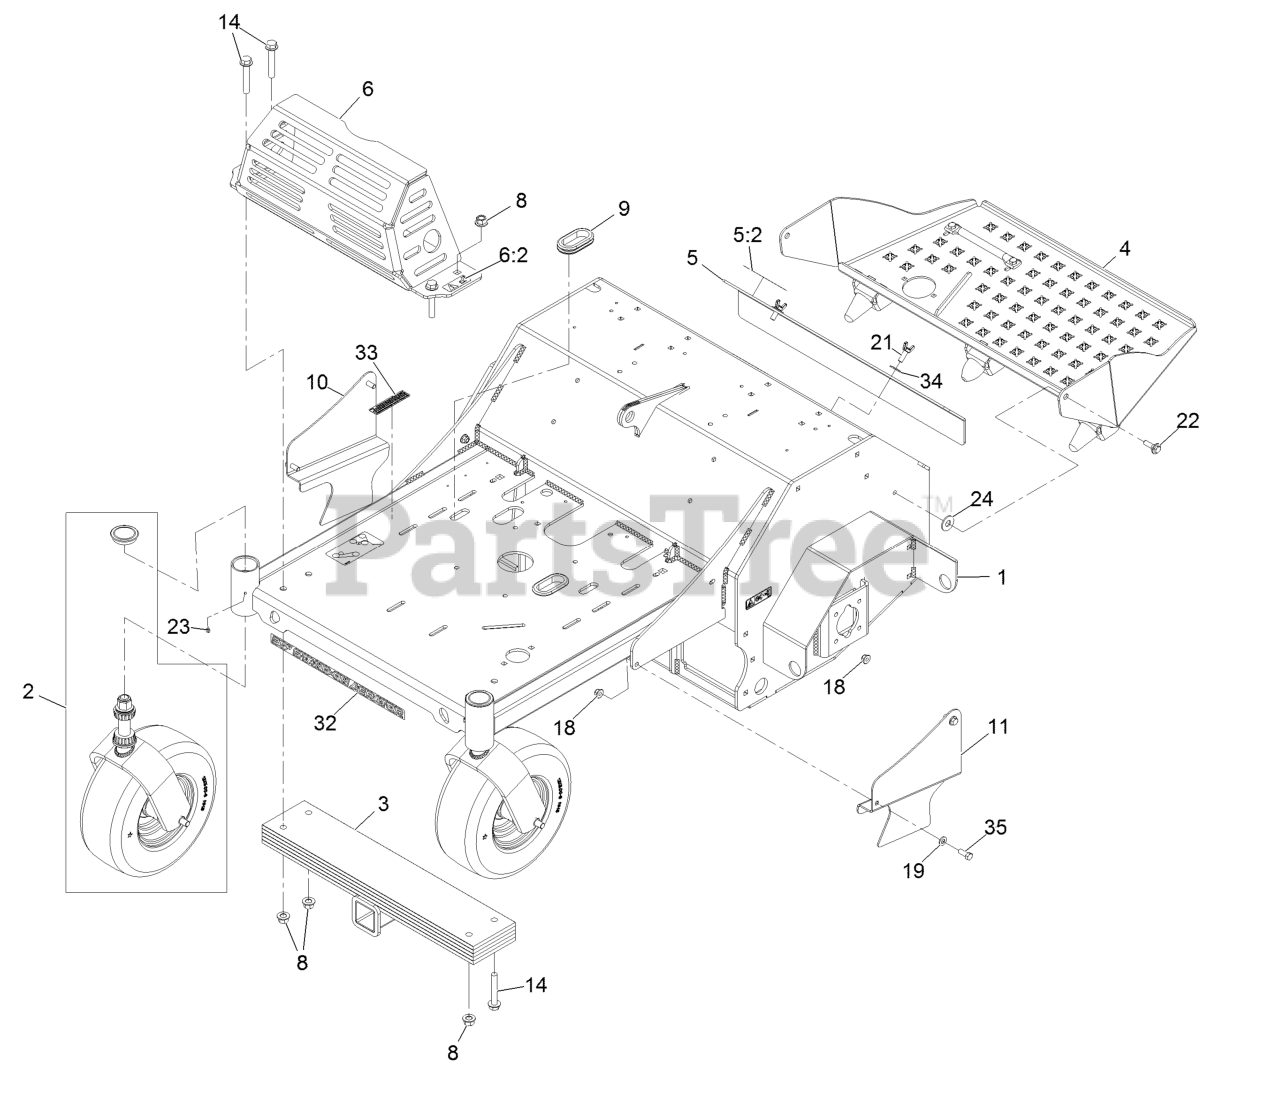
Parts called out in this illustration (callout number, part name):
1	Frame-Main W/Symbol Decals
2	Front Caster ASM W/Fork
4	Platform ASM W/Decal & Rocker
5	Access Cover ASM
5:2	Decal-Tine Ground Operation (CE)
6	Muffler Guard ASM
6:2	Decal-Surface, Hot
8	Nut-Lock 1/2-13
9	Grommet
10	Guard-Chain, RH
11	Guard-Chain, LH
14	Screw-HF
18	Nut-Nyloc 3/8-16 Flg
19	Washer-3/8 SAE
21	Screw-Thumb
22	Screw-Shoulder 3/8-16 X 1.295
24	Washer
32	Decal-Aerator 30 Logo
33	Decal-Arrester, Spark
34	Washer-Spring Disc
35	Screw-HH 3/8-16 X 1
